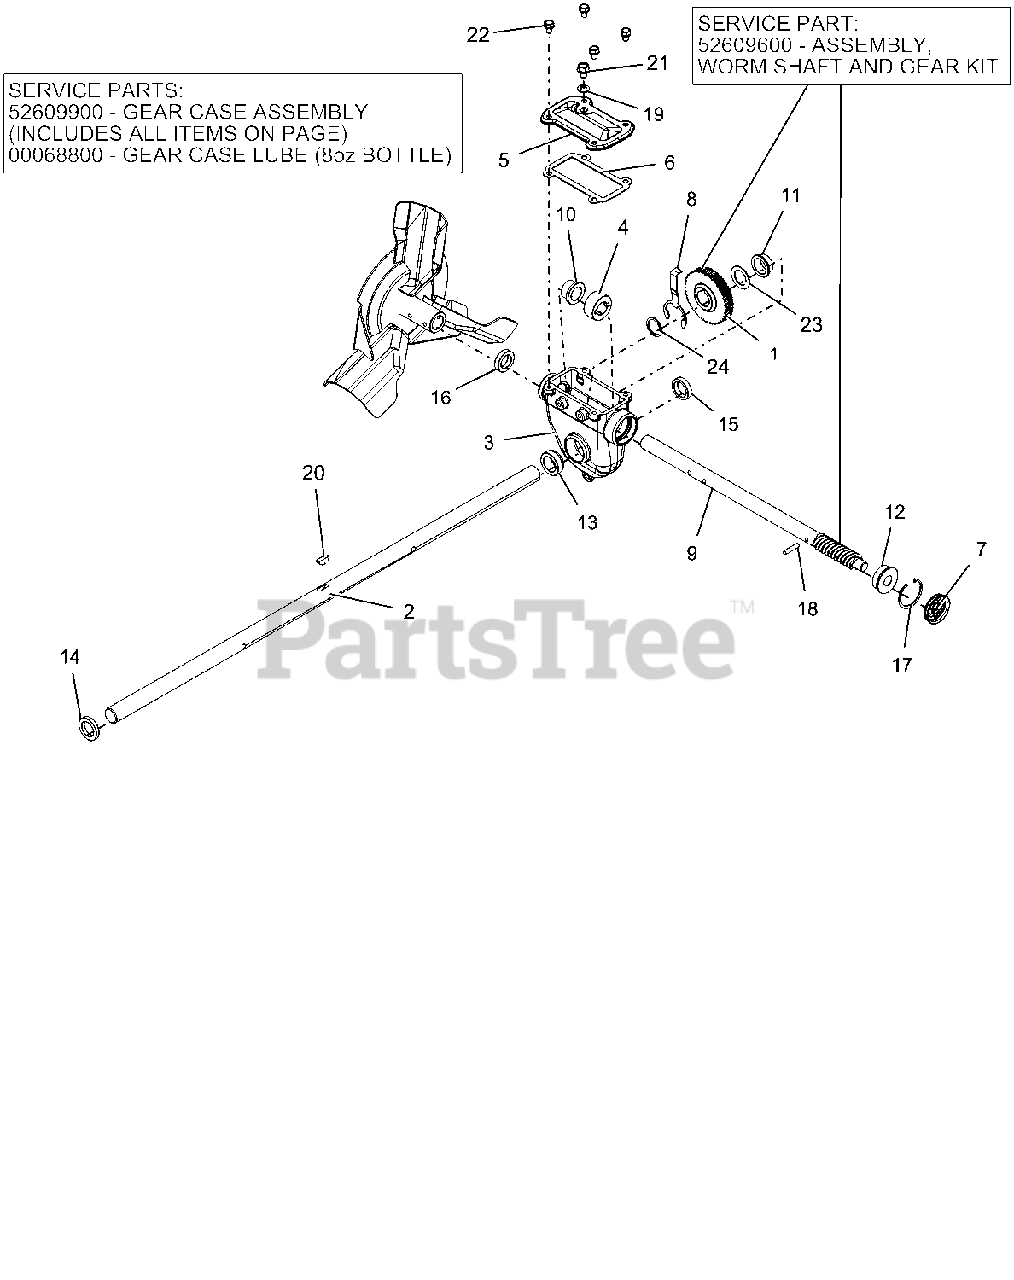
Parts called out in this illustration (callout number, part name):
1	WORM GEAR
2	SHAFT, RAKE-36"
3	GEARCASE, LARGE MACHINED
4	THRUST COLLAR, .875"ID SLIPFIT
5	COVER, TOP - LARGE IRON
6	GASKET, TOP - LARGE GEARCASE
7	COVER, GEAR CASE 1.75"
8	BUSHING RETAINER, LARGE
9	ASSY, WORM SHAFT & GEAR
9	SHAFT, WORM - PRO
10	BSHG-FLG .879X1.128X.75X1.45
11	BSHG-FLG 1.006X1.128X.555X1.45
12	BSHG-FLG .628X1.503X.58X1.725
13	BSHG-FLG LARGE, RIGHT
14	SEAL-OIL .999X1.500X.250 TBC29
15	SEAL-OIL .999X1.375X.312 TBC29
16	SEAL-OIL .873X1.375X.312 TBC29
17	RG-RTNG-INT 1.750X.062
18	PIN-STR .250X1.12 6150
19	WSHR-BND-SEAL .38X.75X.11 GALV
20	KEY-WDRF .25X.875 HRD #A
21	@SCR-ROLOK .38-16X.50 HWH YWZC
22	BOLT, SEMS .31-18X.50 GR5 YWZC
23	WSHR-FL-STL 1.010X1.505X.062YZ
24	WSHR-FL-STL 1.010X1.250X.068YZ
25	GEAR CASE, 36" IRON PRO TOP-LD
26	ARIENS L3 LUBE, 8 OZ BOTTLE
